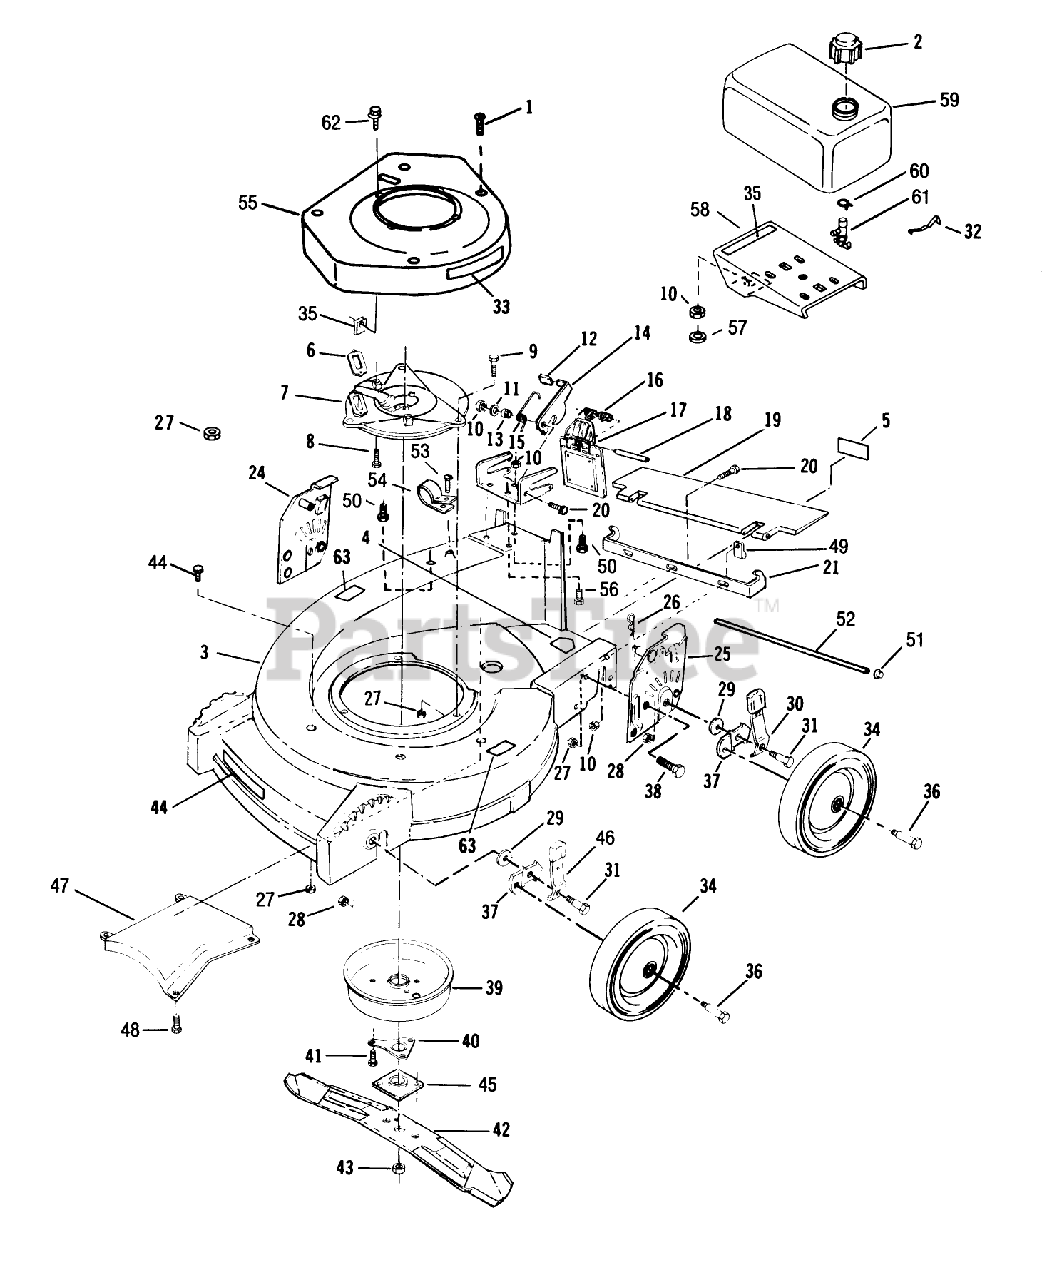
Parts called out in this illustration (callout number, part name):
1	SCREW - SELF TAPPING
2	FUEL CAP & INSERT
7	PLATE F
8	SCREW V
9	SCREW-HH
10	LOCKNUT E
12	KNOB (S&R)
15	SPRING
16	SPRING ASOC
18	ROD (RB&W)
19	T/SHIELD SM&P
26	HAIR PIN
27	NUT-LOCK F
28	LOCKNUT
29	WASHER
31	BOLT
32	SPRING
35	PUSHNUT F
36	BOLT-SHOULDER
39	MUFFLER COVER F
40	SUPPORT F
41	SCREW
43	NUT-BLADE
45	PLATE AND COLLAR ASM
46	SPRING ARM ASM
47	BAFFLE CHUTE PL
50	SCREW HEX WASHER
53	SCREW LAWRENCE
56	SCREW
57	WASHER
58	BRACKET - TANK
60	CLAMP - HOSE S
61	VALVE&SCREEN SM
62	SCREW SEMS SM
